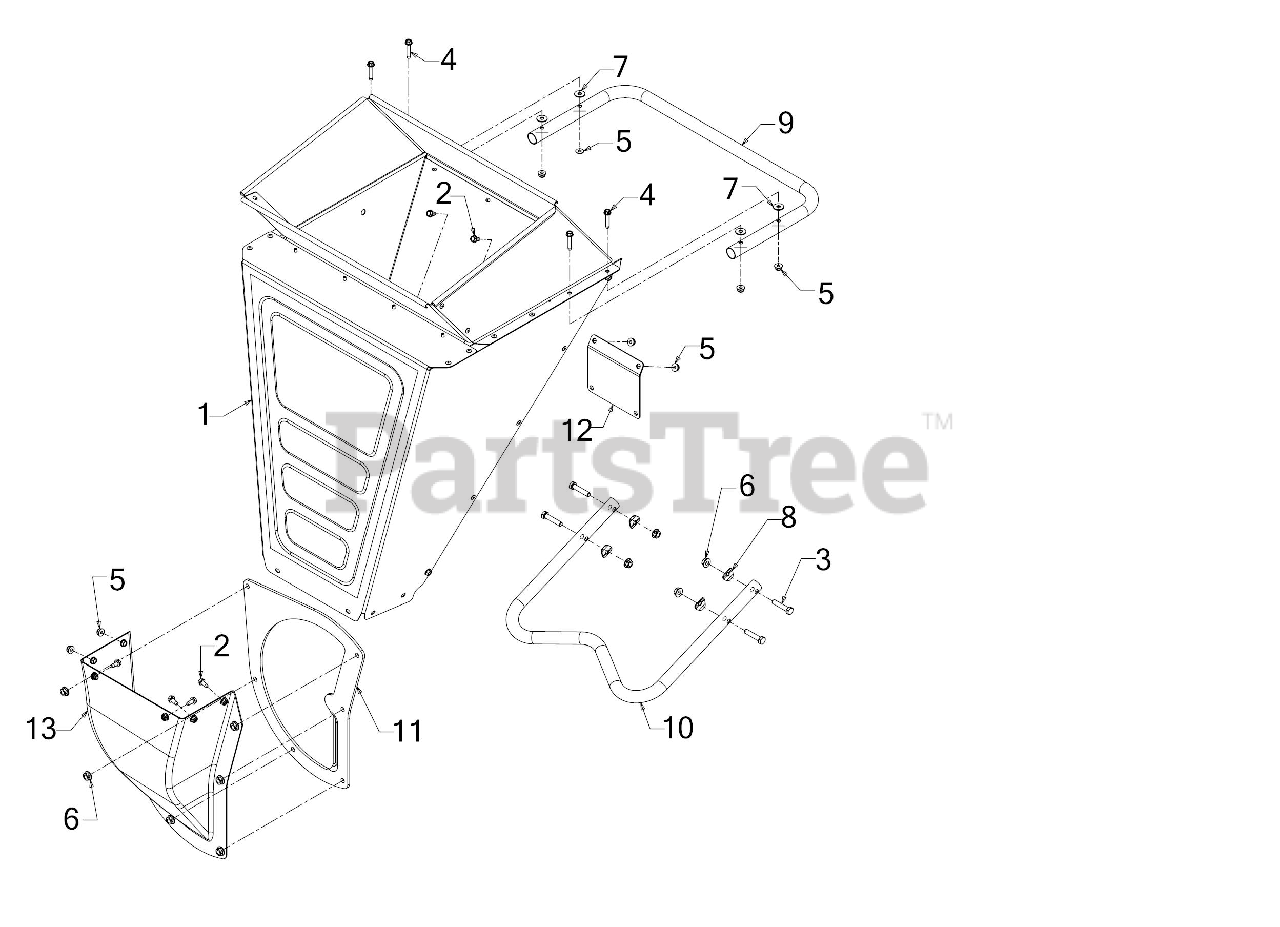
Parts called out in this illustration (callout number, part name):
1	HOPPER ASSEMBLY
2	SCREW 1/4-20 X.500
3	SCREW 5/16-18 x 1.5 LG
4	SCREW 1/4-20 x 1.25
5	FLANGE LOCK NUT
6	HEX FLANGE NUT
7	FLAT WASHER .28 ID x .74 OD x .063
8	SADDLE WASHER
9	HOPPER HANDLE
11	SHREDDER PLATE
12	HOPPER BRACKET SUPPORT
